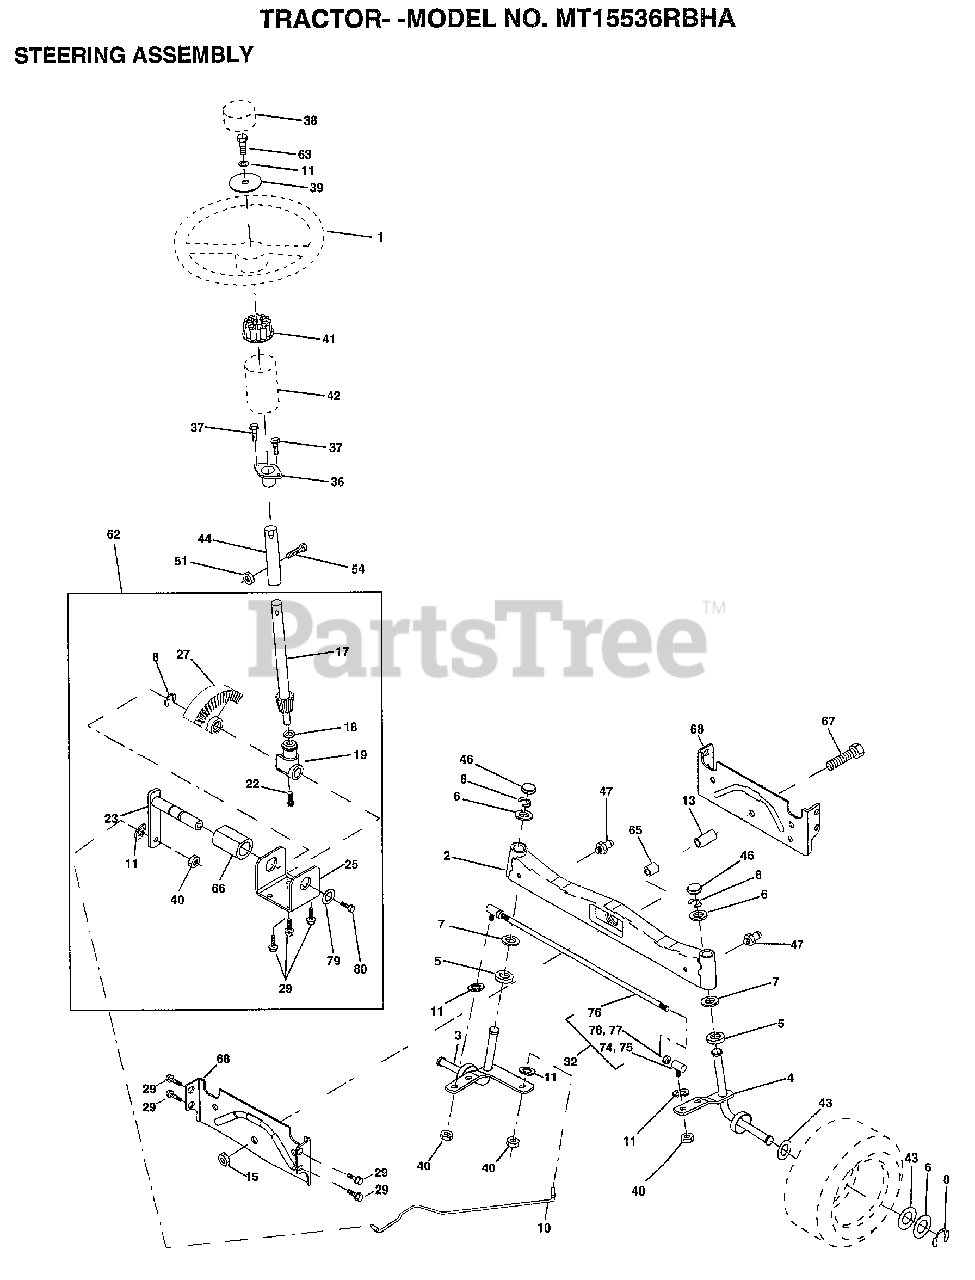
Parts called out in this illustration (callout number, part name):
3	"SPINDLE ASM,LH"
4	"SPINDLE ASM,RH"
5	WASHER .T
6	WASHER
7	WASHER
8	RING
10	LINK.DRAG
11	LOCKWASHER
13	BEARING.FRT.SPACER.AXLE
15	"NUT-LOC,FLANGE LT"
17	SHAFT ASM STEERIN
18	THRUST WASHER
19	SUPPORT.SHAFT.STEER
22	SCREW.HX.WSH.HD
23	SHAFT.ASM.PITMAN
25	BRKT-STEERING
27	GEAR SECTOR
29	SCREW
32	ROD.ASM.TIE.BALL
36	BUSHING.STEERING
37	"SCREW-TT,10-32 FL"
38	"INSERT,STR WHEEL"
39	WASHER T
40	GRIPCO NUT
41	ADAPTER LT
42	BOOT.STEER.PL
43	WASHER
44	EXT SHAFT STEERIN
46	CAP
47	ZERK M
51	NUT
54	BOLT
62	KIT.STEER.ASM
63	BOLT
65	SPACER AXLE
66	"BEARING-ARM,PITMA"
67	BOLT
68	BRACE AXLE
74	JOINT.RH
75	JOINT.LH
77	NUT
78	NUT
79	WASHER
80	BOLT.HX.NYLON3/8-16X3/
